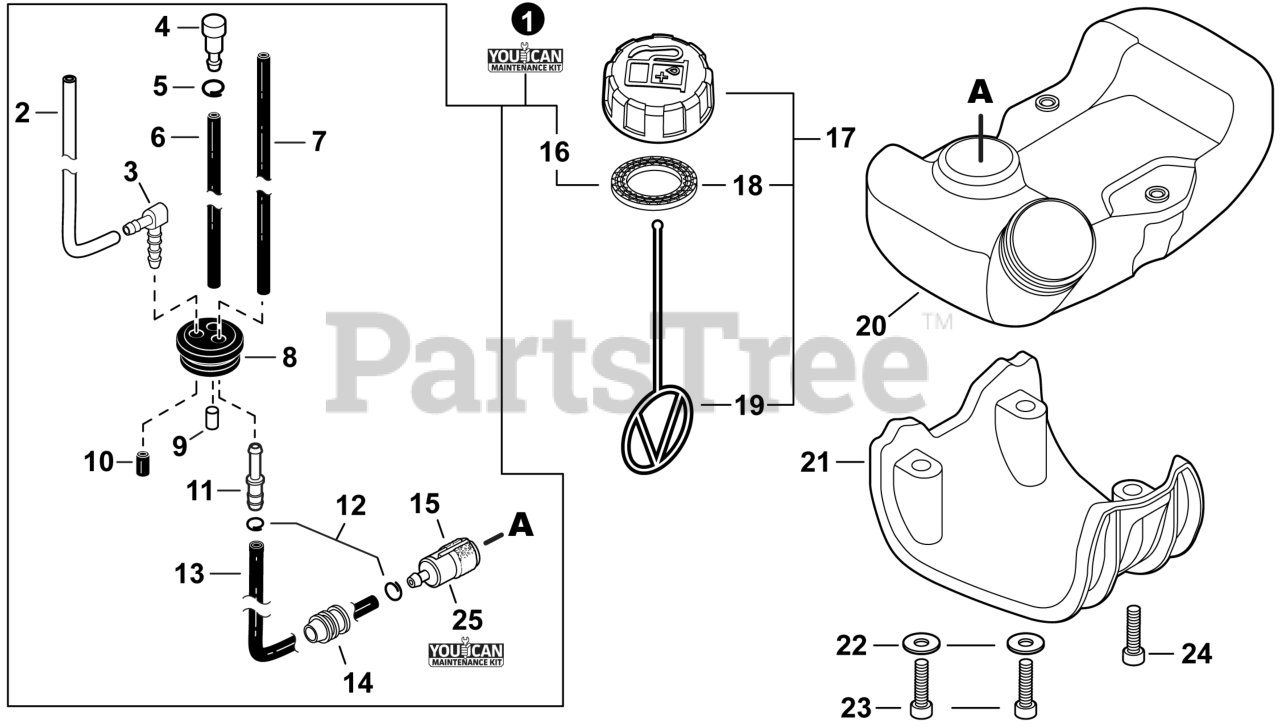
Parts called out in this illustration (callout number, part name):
1	FUEL SYSTEM KIT - YOUCANT
2	PIPE, FUEL 3x6x80 YELLOW
3	CONNECTOR, PIPE
4	VENT ASSY
5	CLIP 6.5 MM
6	PIPE, FUEL 3x6x85 BLACK
7	PIPE, FUEL 3x5.5x83 BLACK
8	GROMMET, FUEL
9	FILTER, VENT
10	PIPE, FUEL 3x7x10 BLACK
11	CONNECTOR, PIPE 5x3.5
13	PIPE, FUEL - 3x5x125 - BLACK
15	FILTER, FUEL
16	GASKET, FUEL CAP
17	CAP ASSY, FUEL
18	GASKET, FUEL CAP
19	CONNECTOR, CAP L= 123
20	TANK, FUEL
21	GUARD, FUEL TANK
22	WASHER 5.5x12x0.8
23	BOLT, TORX 5x25
24	BOLT, TORX 5x20
25	TUNE-UP KIT - YOUCANT
